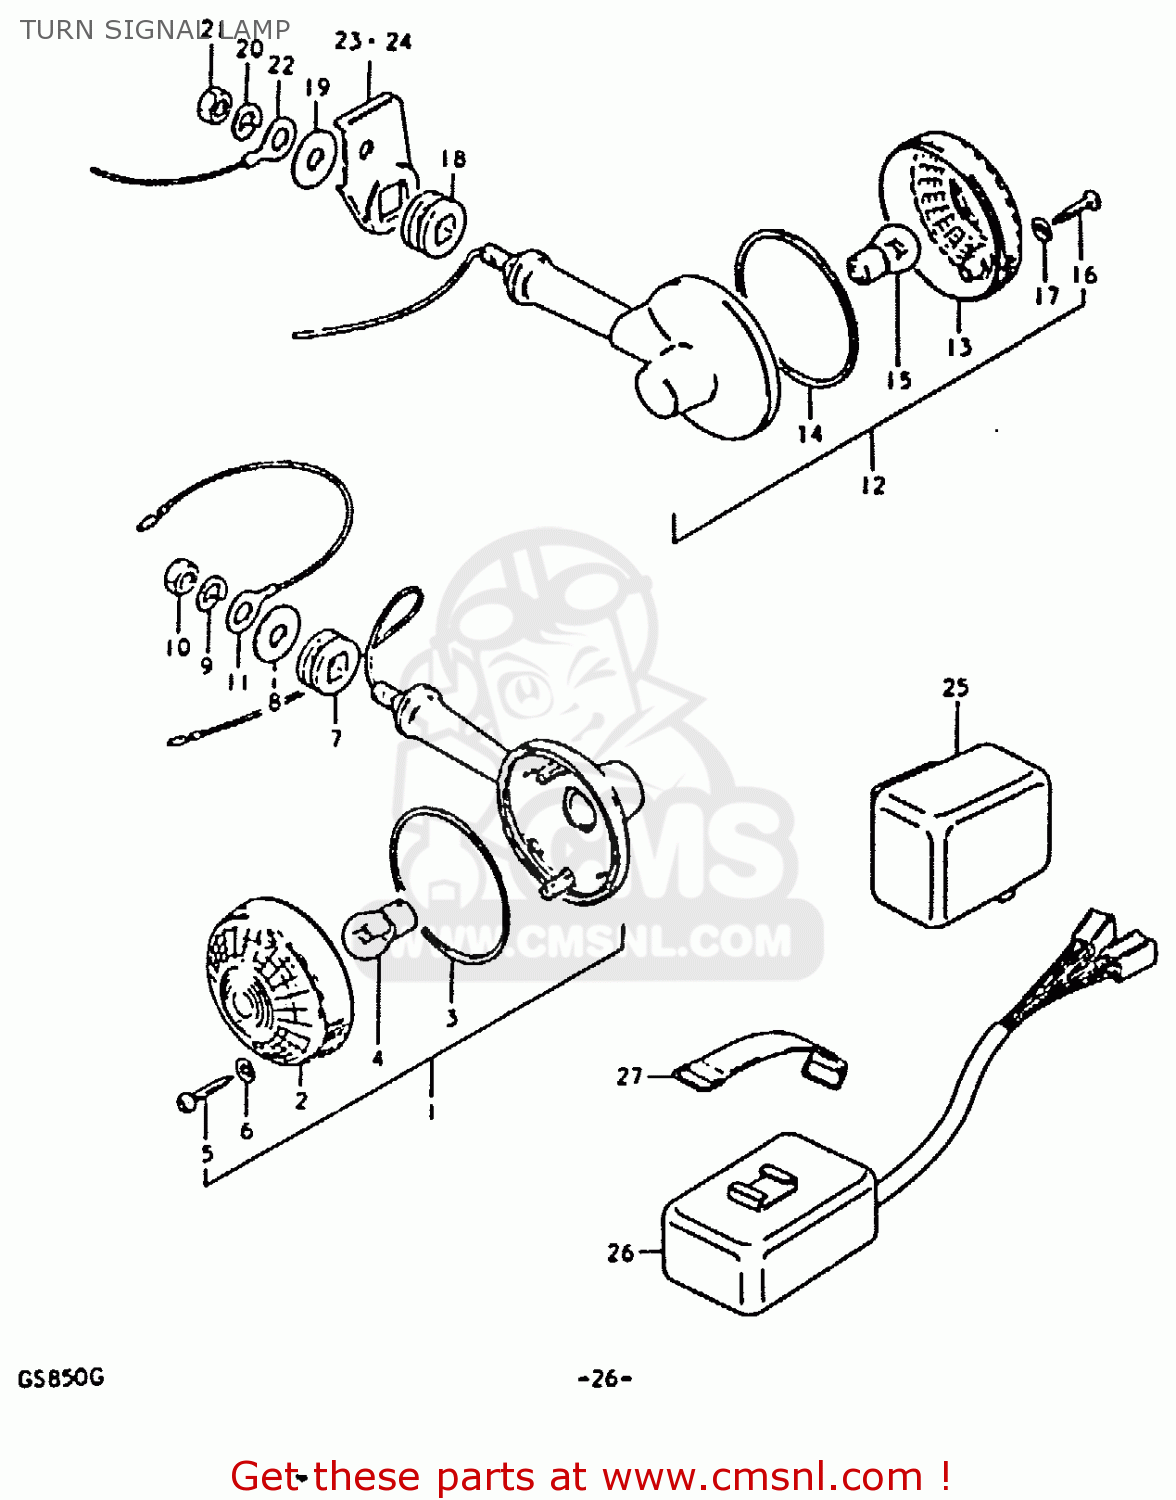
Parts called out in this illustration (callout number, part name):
1	LAMP ASSEMBLY,FRONT TURN SIGNAL
2	LENS
3	GASKET (NAS)
4	BULB(12V23W,STANLEY,A4577A)
5	BOLT
6	GASKET (NAS)
7	CUSHION
8	WASHER
9	LOCK WASHER
10	NUT
11	LEAD WIRE,EARTH
12	LAMP ASSEMBLY,FRONT TURN SIGNAL
13	LENS
14	GASKET (NAS)
15	BULB(12V23W,STANLEY,A4577A)
16	BOLT
17	GASKET (NAS)
18	CUSHION
19	WASHER
20	LOCK WASHER
21	NUT
22	LEAD WIRE,EARTH
23	BRACKET,RR TURNSIGNAL LAMP,R
24	BRACKET,RR TURNSIGNAL LAMP,L
25	RELAY,TURN SIGNAL
26	TURNSIGNAL CONTROL UNIT
27	BAND
